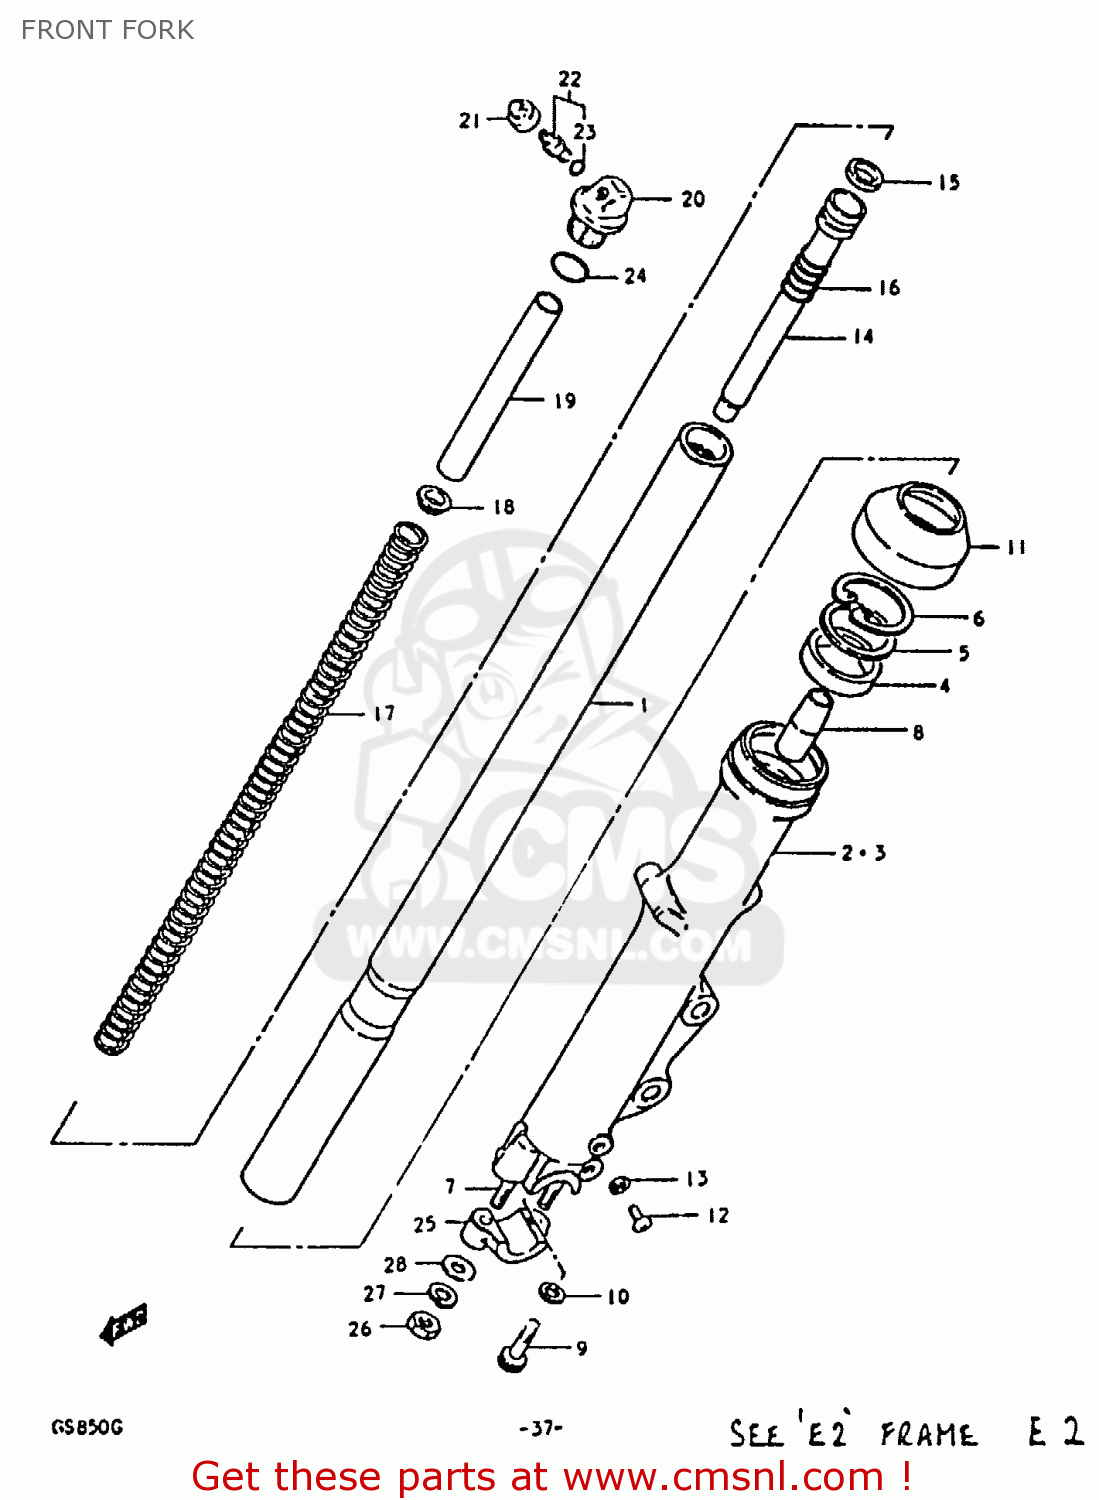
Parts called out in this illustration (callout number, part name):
1	TUBE,FORK,INNER
2	TUBE,FORK,OUTER,RIGHT
3	TUBE,FORK,LEFT,OUTER
4	OIL SEAL,FRONT FORK
5	WASHER. FRONT FORK
6	CIRCLIP,FORK OIL SEAL
7	STUD BOLT
8	PIECE,OIL LOCK
9	BOLT,FORK CYLINDER(10X25)
10	GASKET (NAS)
11	SEAL,DUST
12	SCREW
13	GASKET,DRAIN,PLUG (NAS)
14	CYLINDER,FRONT FORK
15	RING,PISTON
16	SPRING,REBOUND
17	SPRING,FRONT FORK
18	GUIDE,FRONT FORK SPRING C
19	SPACER,SPRING
20	CAP
21	CAP,VALVE
22	VALVE
23	O RING
24	O RING
25	HOLDER,AXLE
26	NUT (8MM)
27	LOCK WASHER
28	WASHER
